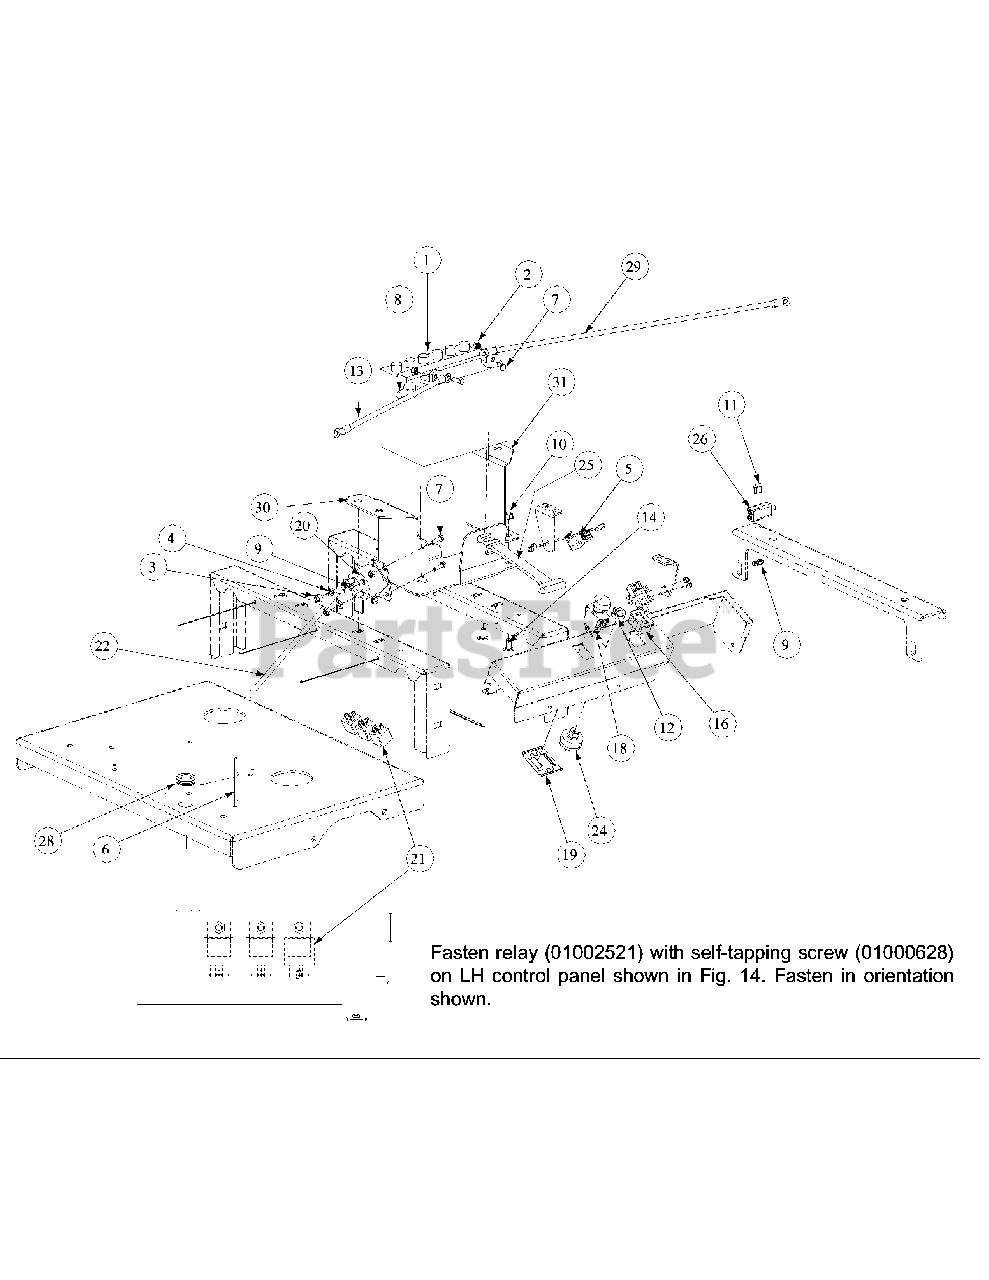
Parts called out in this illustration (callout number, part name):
1	Battery, 12V 225CCA 30 Min
2	Nut, Lock, Nylon Insert, 1/4-20
3	Nylock Nut, 5/16-18
4	Lock Washer, 5/16
5	Switch, Safety
6	Tie, Cable, 3/16 x .05 x 7.4"
7	Screw, Hex, Cap, 1/4-20 x .75
8	Boot, 1" OD Rubber Battery-PST, Red
9	Nut, Lock, Nylon Insert, #10-32
10	Nut, Hex, Flange Lock, 3/8-16
11	Screw, Phillips Head, Machine, 10-32 x 5/8
12	Nut, W/Cap, 5/8-32 Ignition
13	Cable, Battery, Red, 15"
14	Carriage Bolt, 3/8-16 x .75 LG.
16	Meter, Hour
18	Switch, Electric, PTO
19	Bracket, PTO Switch Retainer
20	Solenoid Magnetic Switch
21	Relay, 12V 40A
22	Cable, Battery Red, 32"
24	Switch, Ignition, 6 Pin
24	Key, Ignition
25	Strap, Battery
26	Switch, Plunger
28	Grommet, .75 ID
29	Cable, Battery Red, 24"
30	Mount Bracket, Battery
31	Mount Bracket, Battery
